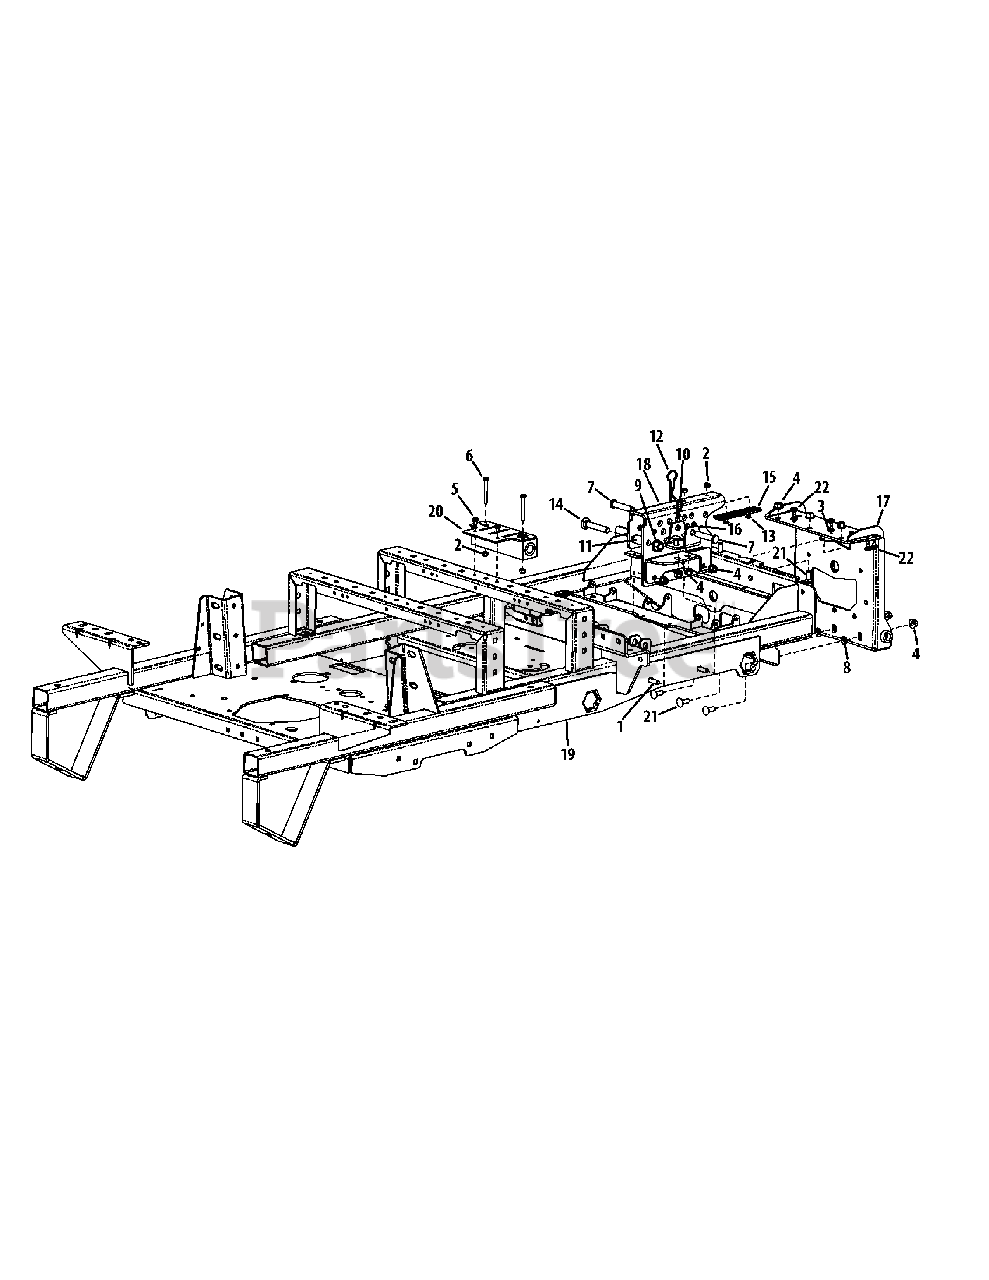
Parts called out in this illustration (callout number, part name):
1	Carriage Bolt, 3/8-16 x 1.25
2	Nylock Nut, 1/4-20
3	Washer. .344 x .688 x .063
4	Flange Counterlock Nut, 3/8-16
5	Hex Flange Screw, 1/4-20 x .500
6	Hex Screw, 1/4-20 x 2.25
7	Clevis Pin, 1/2 x 2.500
8	Push Nut, .335 x .780 x .015
9	Flange Top Lock Nut, 1/2-13
10	Hair Pin, 1/2 x 1.625 x .125
11	Spacer, .510 x .750 x 1.25
12	Hitch Pin, .120 X 3.00
13	Flat Screw, 1/4-20 X .750
14	Carriage Bolt, 1/2-13 X 3.00
15	Wear Plate, 1.125 x 5.0
16	Cylinder Mount Bracket
17	Front Axle Brakcet Assembly
18	Index Lift Housing Assembly
19	Frame Assembly
20	Manifold Mount Bracket
21	Carriage Bolt, 3/8-16 x 1.00
22	Rubber Bumper, .62 x .22
